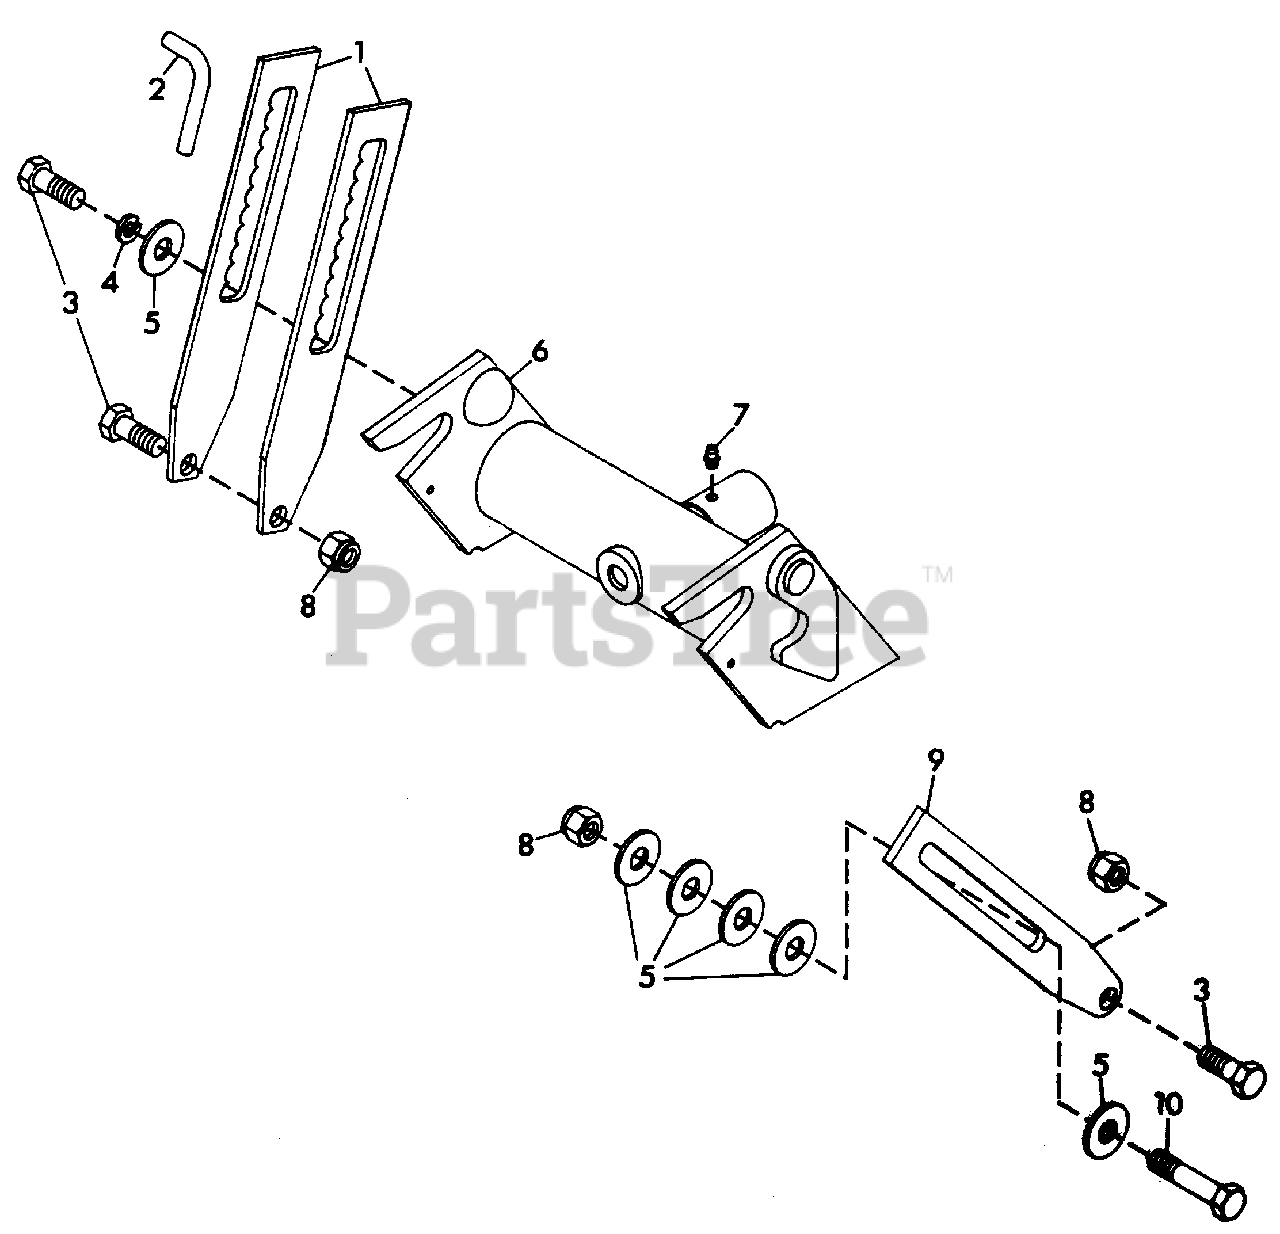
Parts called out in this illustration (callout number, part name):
1	Strap
2	Pin
3	Bolt, Hex 1/2-13x1.25
4	Washer, Lock 1/2 Reg.
5	Washer, Flat 1.38x.56 Hard
6	Weldment, Adapter
7	Fitting, Lube 1/4-28
8	Nut, Lock 1/2-13
9	Strap
10	Bolt, Hex 1/2-13x2.25
